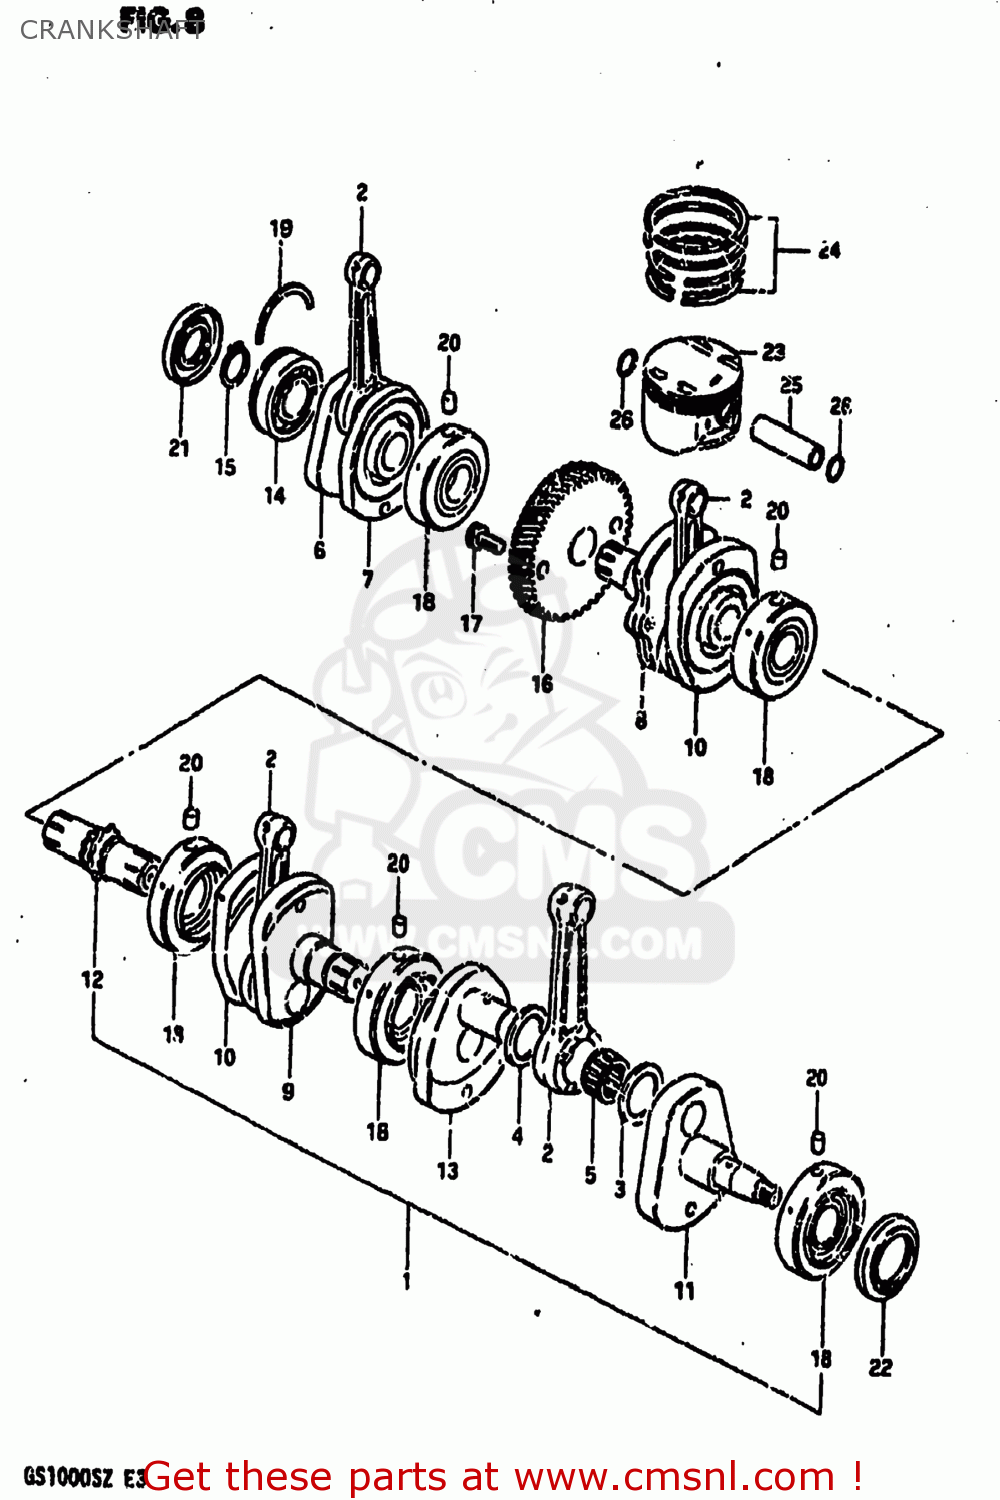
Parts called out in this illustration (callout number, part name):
1	CRANKSHAFT ASS
2	ROD,CONNECTING
3	WASHER(31X48.5X1)
4	WASHER(31X48.5X2)
5	BEARING(31X39X21)
6	CRANKSHAFT,RIGHT
7	WEB,CRANK
8	CRANKSHAFT
9	CRANKSHAFT,MIDDLE,LEFT
10	WEB,CRANK,MIDDLE
11	CRANKSHAFT,LEFT
12	SHAFT,TIMING CHAIN DRIVE
13	WEB,CRANK,LEFT
14	BEARING(30X72X19)
15	CIRCLIP,30MM
16	GEAR,PRIMARY DRIVE
17	BOLT
18	BEARING
19	C RING
20	PIN
21	SEAL,OIL(30X72X11)
22	OIL SEAL
23	PISTON (STD)
24	RING SET,PISTON
25	PIN,PISTON
26	CIRCLIP
